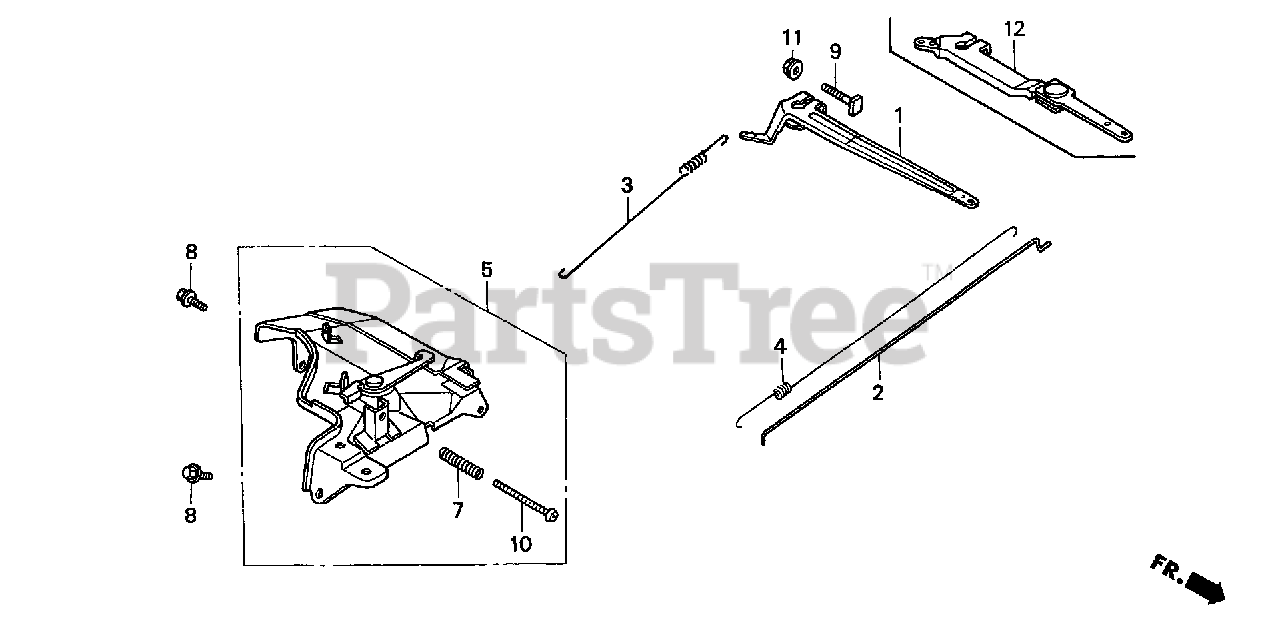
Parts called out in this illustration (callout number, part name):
1	ARM, GOVERNOR
2	ROD, GOVERNOR
3	SPRING, GOVERNOR
4	SPRING, THROTTLE RETURN
5	CONTROL ASSY.
7	SPRING, CONTROL ADJUSTING
8	BOLT, FLANGE (6X12) (CT200)
9	BOLT, GOVERNOR ARM
10	SCREW, PAN (5X45)
11	NUT, FLANGE (6MM)
